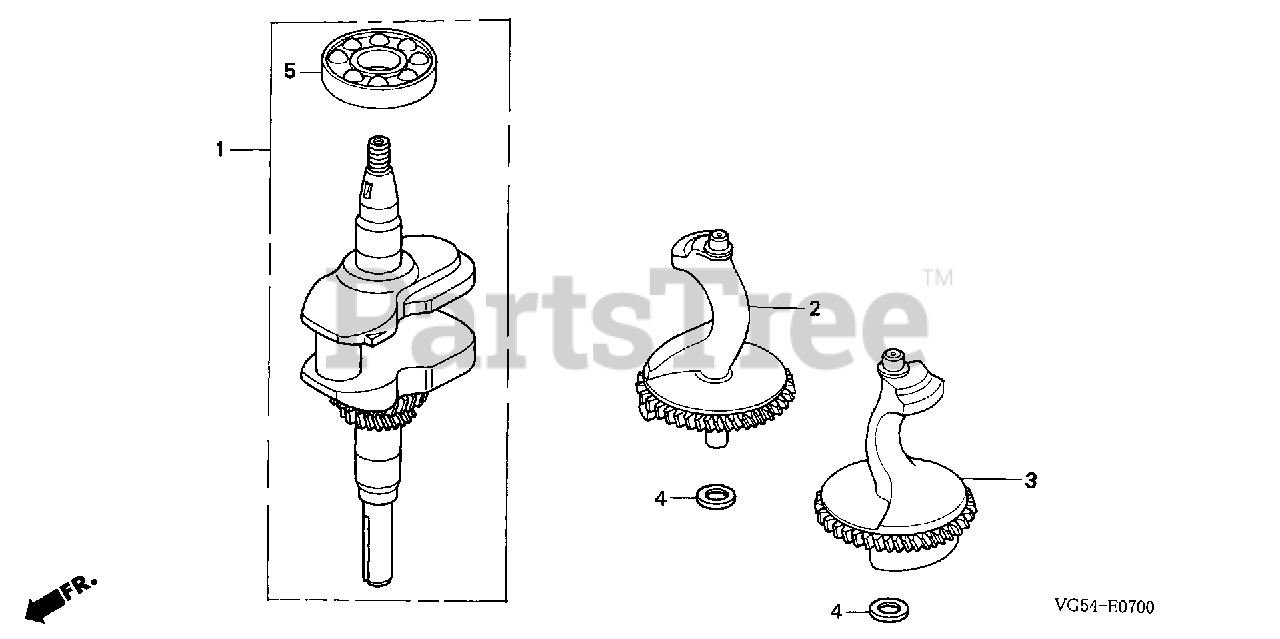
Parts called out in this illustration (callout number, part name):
1	CRANKSHAFT
2	WEIGHT A, BALANCER
3	WEIGHT B, BALANCER
4	WASHER, THRUST (14MM)
5	BEARING, RADIAL BALL (6207)
